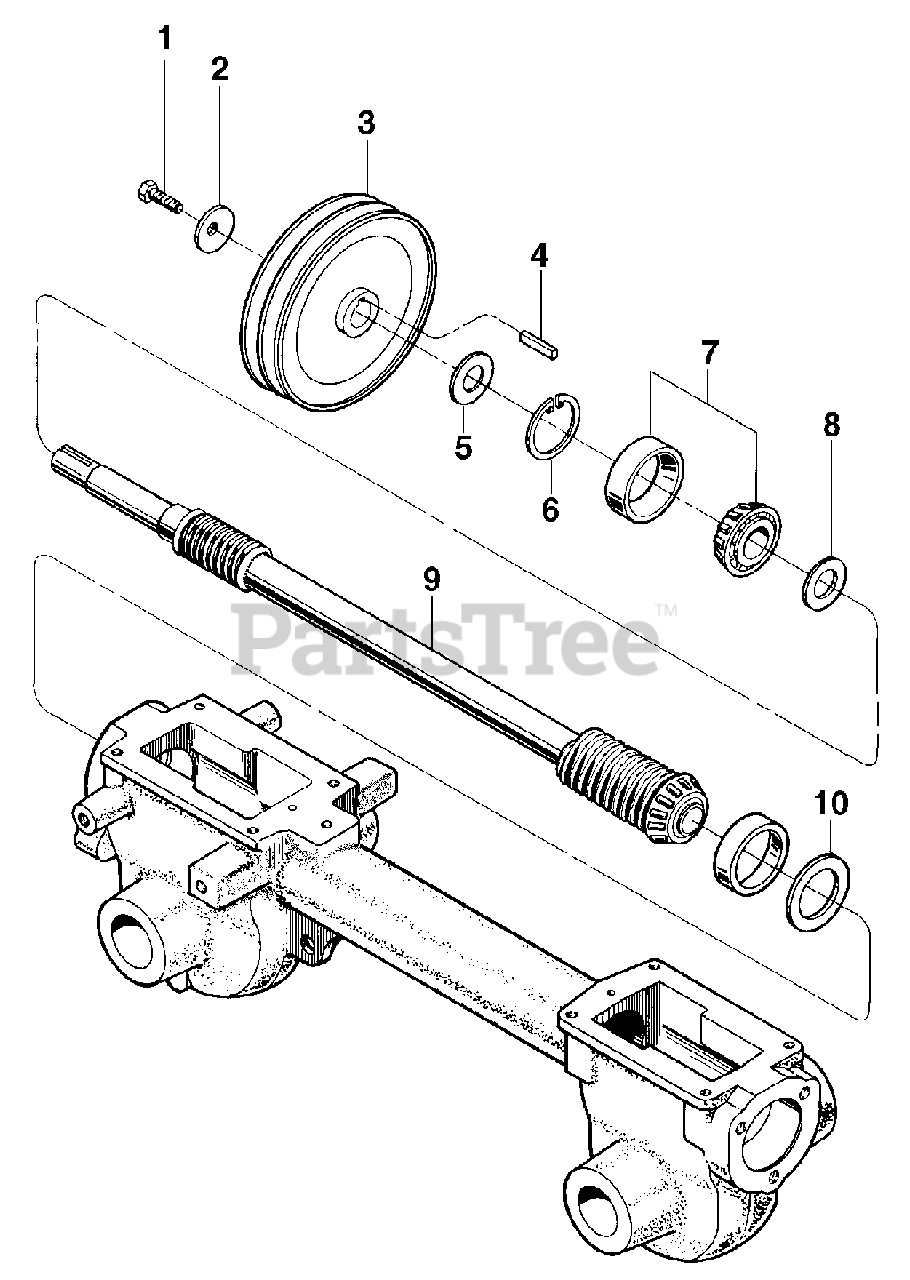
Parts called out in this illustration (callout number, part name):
1	Hex Screw, 5/16-24 x 3/4, Grade 5
2	Belleville Washer
3	Transmission Pulley
4	Key, Transmission Pulley, 3/16 x 1
5	Support Washer, Front
6	Snap Ring
7	Bearing, Tapered Roller (with race)
8	Support Washer, Rear
9	Drive Shaft Ass'y
10	Shim, Rear Bearing Cap, .010" thick
